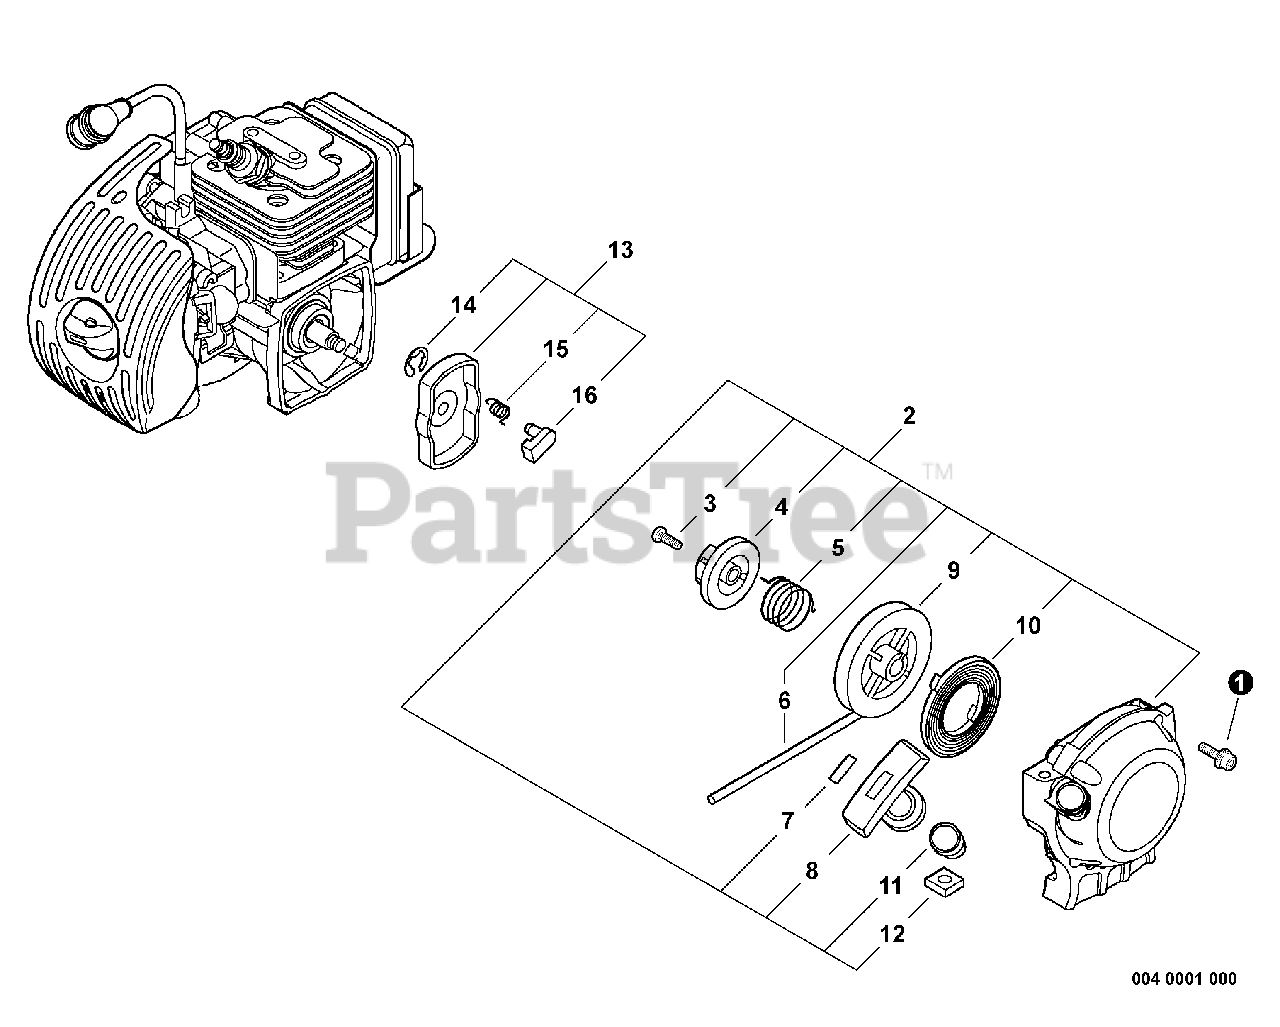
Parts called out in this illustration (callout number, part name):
1	BOLT 4×16
2	STARTER ASSY, RECOIL
3	SCREW
4	PLATE, CAM (NLA SEE PB 15-06)
5	SPRING, TORSION
6	ROPE, STARTER 3×700
7	RETAINER, ROPE
8	GRIP, STARTER
9	REEL, ROPE
10	SPRING, RECOIL
11	GUIDE, ROPE
12	NUT M5
13	PAWL ASSY, STARTER
14	E-RING 4
15	SPRING, RETURN
16	PAWL, STARTER
